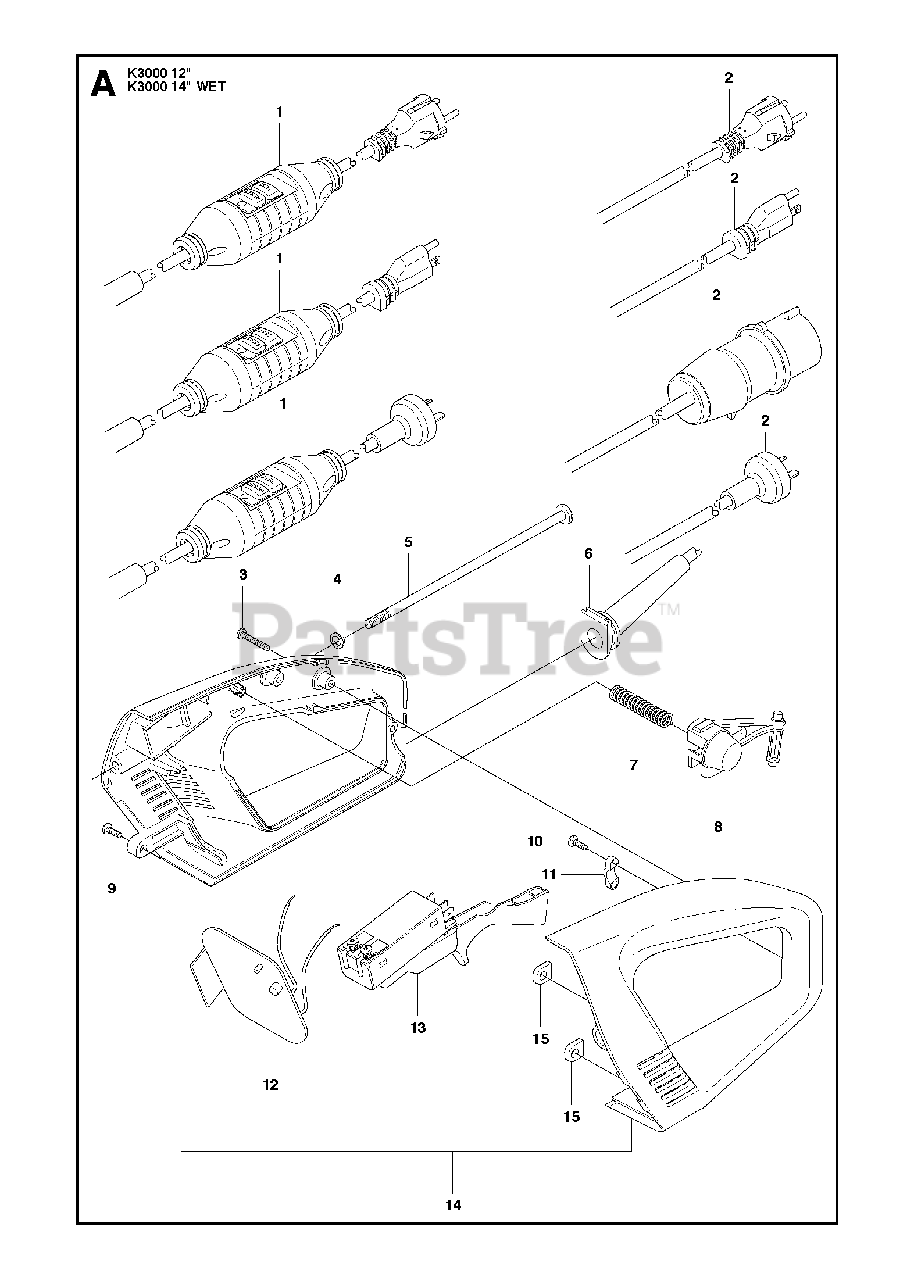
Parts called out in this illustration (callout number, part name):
1	CABLE110V JP, USA
1	CABLE110V AU, Incl. 6
2	CABLE ASSY230V
2	CABLE110V JP, USA
4	SPRING WASHER
6	CABLE SLEEVE230V
7	SPRING
8	LOCKING BUTTON
9	SCREW CRPANM
12	PRINTED CIRCUIT ASSY110V
12	PRINTED CIRCUIT ASSY230V
14	HANDLE ASSY
